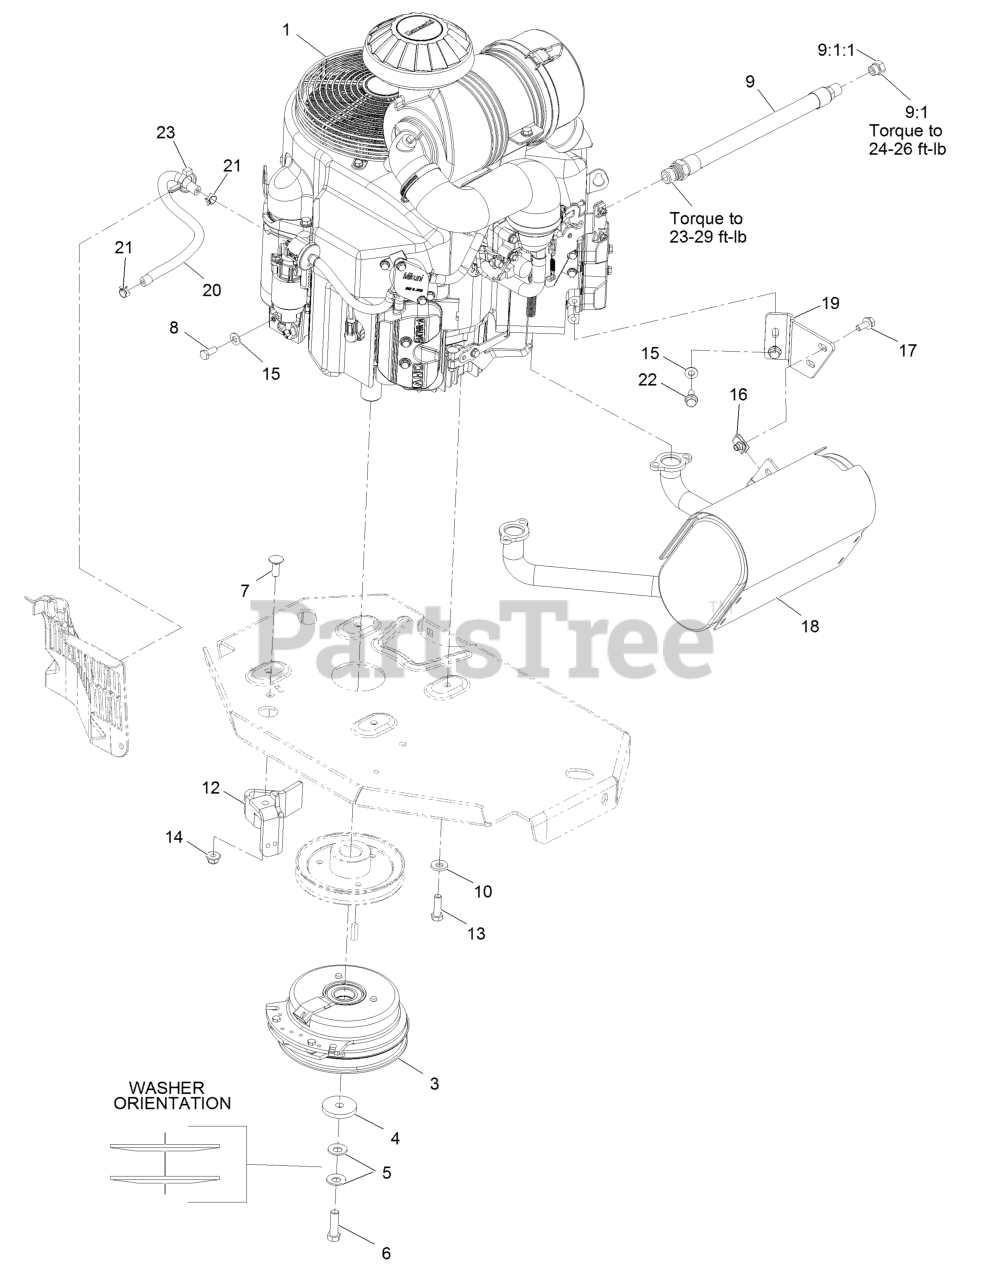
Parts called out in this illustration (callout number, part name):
3	CLUTCH KIT
4	WASHER-CLUTCH
5	WASHER-SPRING
6	SCREW-HH 7/16-20 X 1 1/2 W/LOCTITE
7	SCREW-CARR
8	SCREW-HH
9	ENGINE OIL DRAIN HOSE ASM
9:1	PLUG-HH
9:1:1	O-RING
10	WASHER-BELLEVILLE
12	CLUTCH-ANCHOR
13	SCREW-HH
14	NUT-HF, NI
15	WASHER-SPRING
17	SCREW-HHF
18	MUFFLER
19	BRACKET-MUFFLER
20	HOSE-FUEL
21	CLAMP-HOSE
22	SCREW-HHF
23	CLAMP-HOSE
